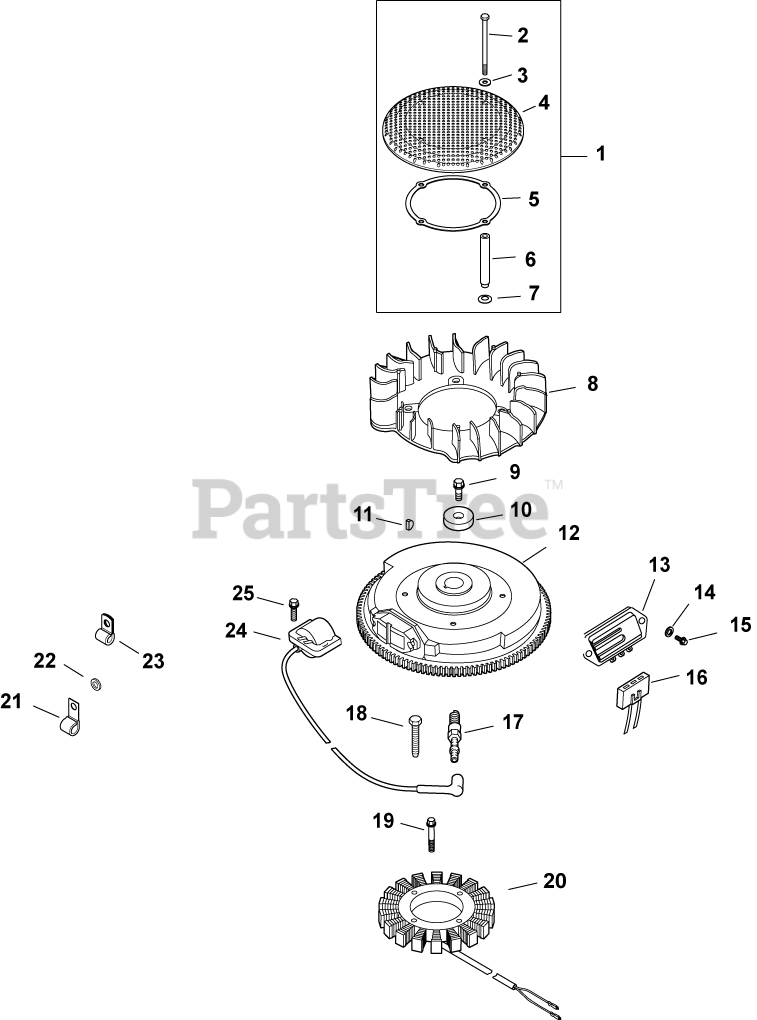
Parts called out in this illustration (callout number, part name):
1	KIT, CHOPPER SCREEN
2	SCREW, CAP M6X1.0X99.5
3	WASHER, FLAT 1/4" (O.D. 5/8")
4	SCREEN, GRASS
5	RING, SUPPORT USE 25 141 08-S
7	WASHER, SPRING 10 MM
8	FAN USE 24 755 253-S
9	SCREW, FLG M10X1.5X45 - (#25086361S)
10	WASHER, FLAT 13/32"
11	KEY, 3/16" X 5/8"
12	FLYWHEEL, PAINTED-USE 24 025 59-S
13	REG/RECT-15 AMP (KM)-USE 41 403 10-S
14	WASHER, FLAT 3/16"
15	SCREW, PHL HD #11-16X7/8"
16	CONNECTOR, BODY (KM)-USE 25 155 41-S
17	PLUG, SPARK (STD)
18	SCREW, M5X0.8X25 - (#25086402S)
19	SCREW, SKT SET #10-24X1/4"
20	KIT, 15 / 20 AMP STATOR
21	CLIP, TUBE & WIRING (KM)
22	WASHER, FLAT 1/4" (O.D. 1/2")
23	CLIP, CABLE
24	KIT, MODULE IGNTN (CDI FIXED)
25	SCREW, FLG THD FRM M5X.8X20-(#25086399S)
